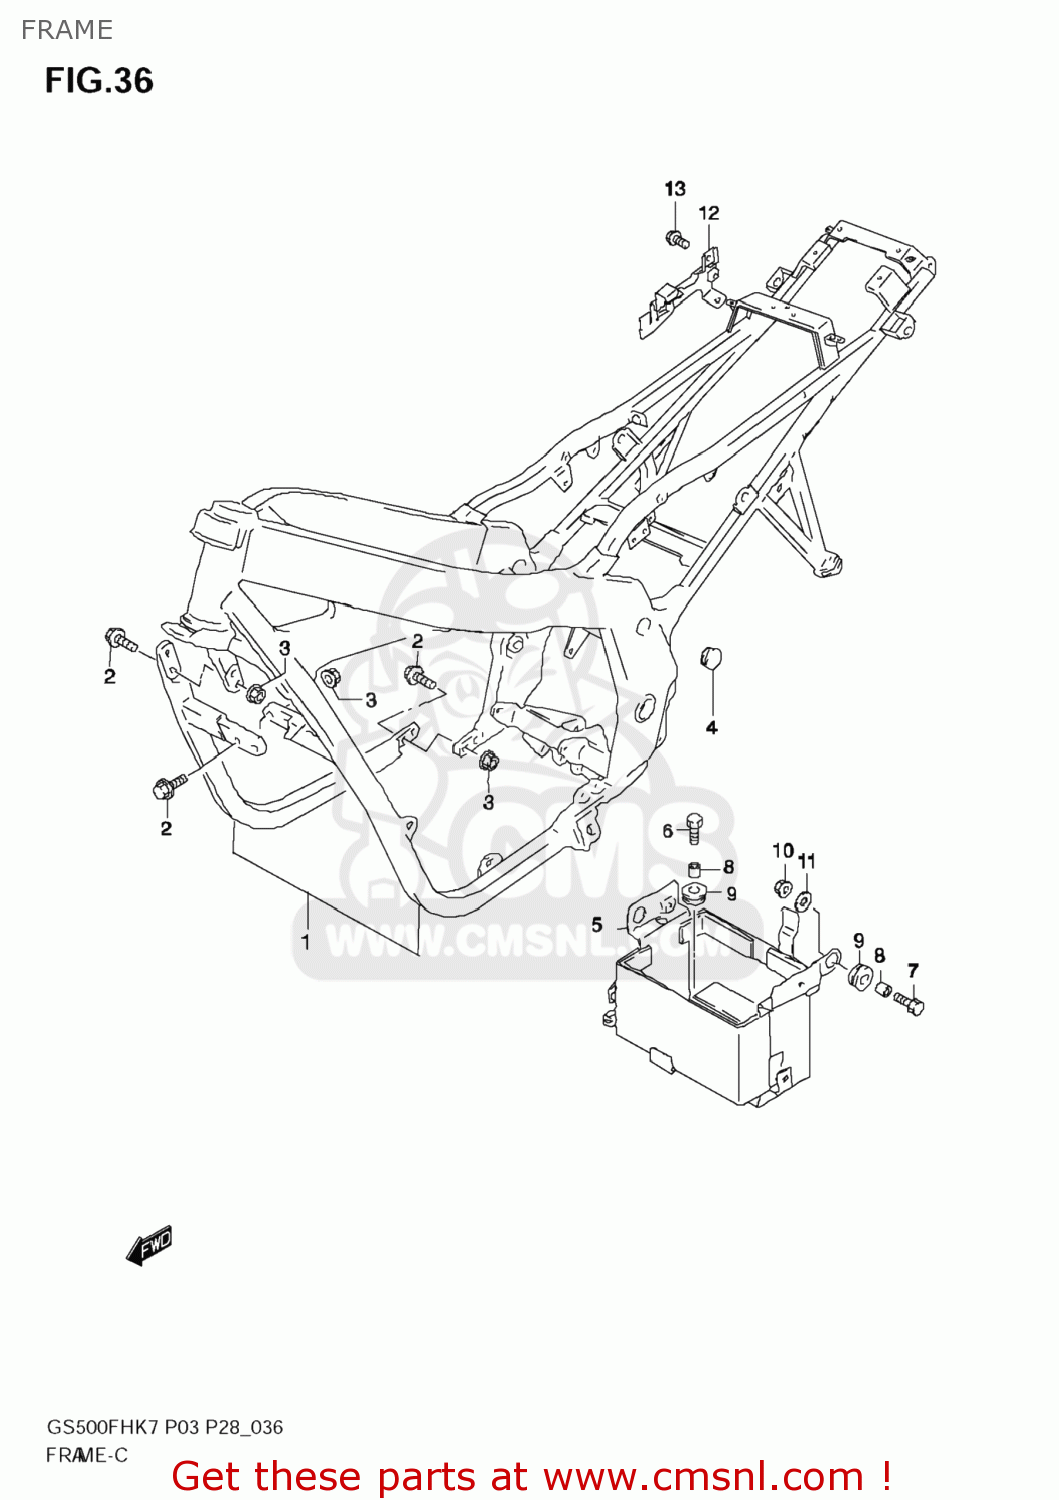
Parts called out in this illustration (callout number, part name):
1	FRAME SET
2	BOLT
3	NUT
4	CAP,BODY FRAME
5	HOLDER,BATTERY
6	BOLT 6X16
7	BOLT
8	SPACER(6.1X9X7.5)
9	CUSHION
10	NUT
11	WASHER GS500/K
12	HOLDER,ELECTRIC PARTS
13	BOLT UH125&200
